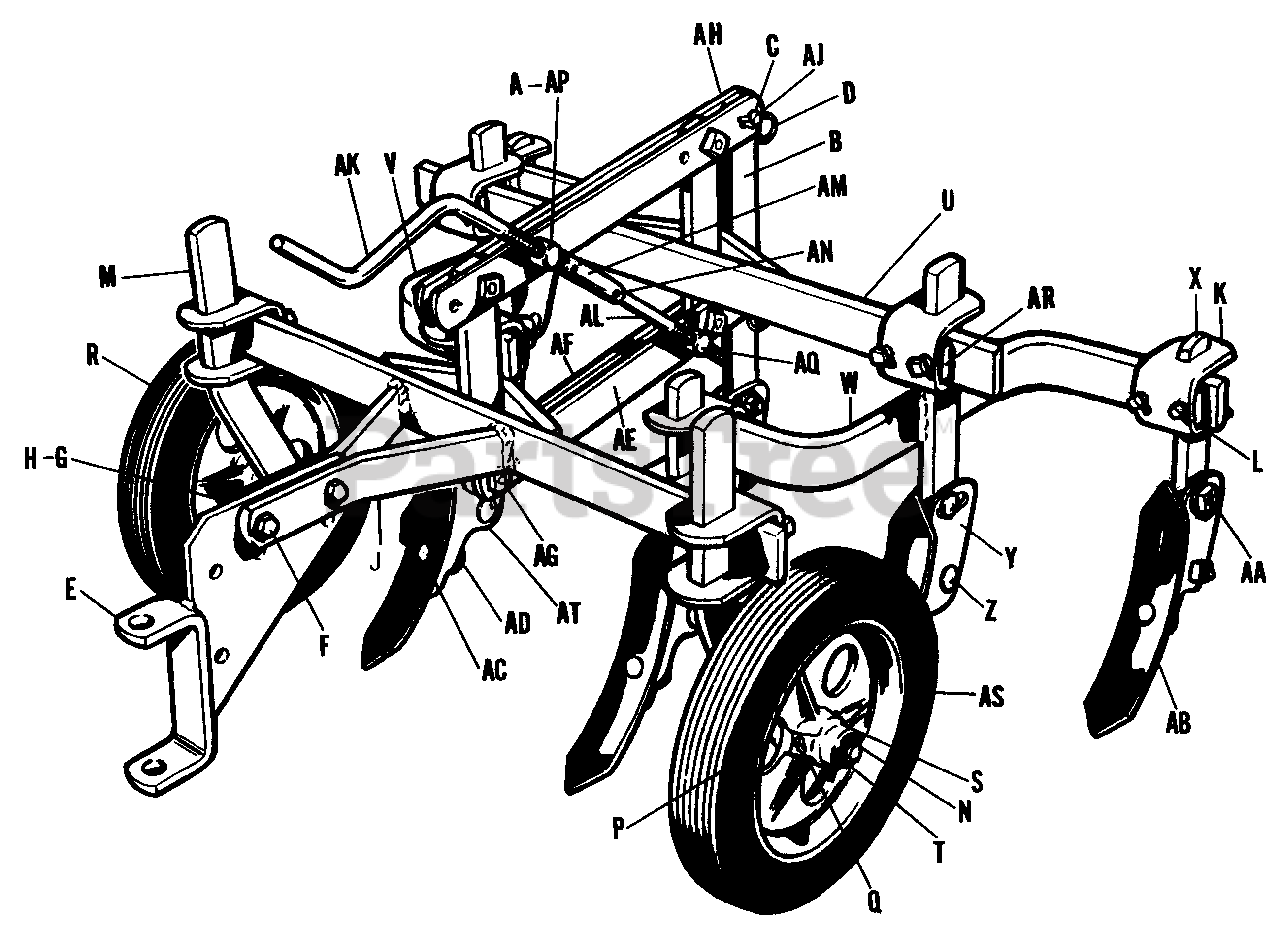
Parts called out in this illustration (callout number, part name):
A	Pin, Cotter, 1/8" dia. x 1" LG.
D	Spring Clip
E	End Assembly, Drawbar
F	Bolt, Carriage, 3/8-16 x 1-1/2"
G	Washer, Lock, 3/8"
H	Nut, Hex., Full, 3/8"-16 NC
J	Drawbar Assembly
K	Clamp, Shank
L	Screw, Set, 3/8"-16 x 1" lg.
M	Standard, Wheel
N	Spindle, Wheel
P	Nut, Jam, Hex., 5/8"-11 NC
Q	Fitting, Grease
R	Wheel, Complete
T	Pin, Cotter, 1/8" dia. x 1"
U	Tool Bar Assembly
V	Frame Assembly, Tool, R.H.
W	Frame Assembly, Tool, L.H.
X	Standard, Tool, Short
Y	Tool Holder Assembly
Z	Bolt, Carriage, 3/8-16 x 1-1/4"
AA	Washer, Plain, 3/8"
AB	Steel, Cultivator
AC	Bolt, Plow
AD	Washer, Plain, 3/8"
AE	Bar, Parallel, R.H.
AF	Bar, Parallel, L.H.
AG	Capscrew, Hex, 3/8"-16 x 1-1/4"
AH	Bar, Parallel, R.H.
AJ	Bar, Parallel, L.H.
AK	Screw, Upper
AL	Screw, Lower
AM	Coupling, Screw
AN	Rivet, Round Head
AP	Nut, Adj., Upper
AQ	Nut, Adj., Lower
AR	Nut, Special
AS	Tire Only, 10 x 1.75
